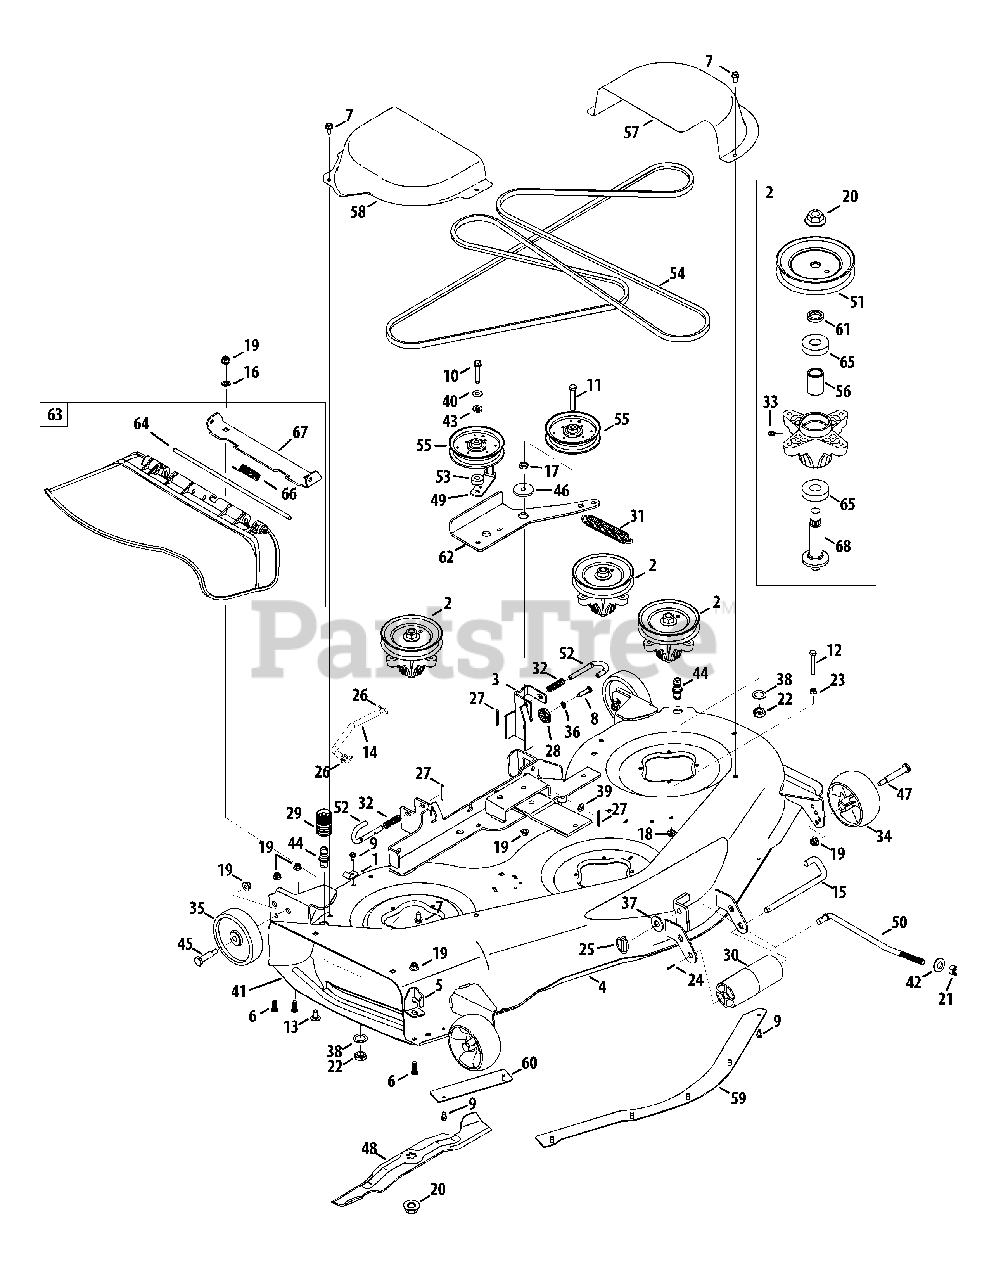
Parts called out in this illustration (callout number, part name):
1	Retainer Hook Brkt.
2	Spindle Assembly
3	Deck Hanger Bracket Ass'y
4	Deck Assembly
5	Chute Deflector Stop
6	Screw, 3/8-16 x 1.0
7	Hex Wash Hd. Tapp Screw. 5/16-18 x .75
8	Hex Bolt 5/16-18 x 1.25
9	Hex Wash S-Tapp Screw 1/4-20 x .50
10	Hex Wash S-Tapp Screw 5/16-16 x 1.875
11	Hex Bolt 3/8-16 x 2.25
12	Hex Hd Cap Screw. 5/16-18 x 2.0 Gr. 5
13	Short Neck Car riage Bolt 3/8-16 x .75
14	Deck Support Rod
15	Roller Pin
16	Push Nut 3/8
17	Jam Nut 7/16 -20, Gr. 2
18	Flange Locknut 5/16-18 Gr. F, Nylon
19	Flange Lock-Nut 3/8-16 Gr. F Nylon
20	Flange Nut 5/8-18
21	Flexlock Nut 1/2-13
22	Hex Nut M16-1.5 DIN 936
23	Hex Nut 5/16-18 hd. (Gr. t5)
24	Cotter Pin 3/32 x 1.0
25	Lynch Pin, .1875
26	Bow Tie Cotter Pin
27	Cotter Pin 1/8" Dia x 1.25
28	Deck adjustment Gear
29	Water Nozzle Adap tor
30	Front Roller
31	Extension Spring 1.0 x 6.10
32	Compression Spring .535 OD x 1.75" Lg.
33	Grease Fitting
34	Deck Wheel 5.0
35	Wheel Ass’y - Deck 5" x 1.38"
36	L-Wash 5/16 ID
37	Flat Washer .531 ID x 1.25 OD x .100
38	L-Washer Internal
39	Flat Washer .344 ID x .688 OD x .065
40	Flat Washer .406 ID x .875 OD x .059
41	Finger Guard
42	Cupped Washer .63 x 1.25 x .18
43	Flat Washer .407 ID x .812 OD x .135
44	Port, Water
45	Shoulder Bolt .498 Dia x 1.53 x 3/8-16
46	Spacer, Shoulder .884 x .190
47	Shoulder Screw
48	Blade 17.90
49	Belt Guard Bracket
50	Front Deck Lift Rod
51	Idler Pulley
52	Deck Release Pin
53	Spacer .406 x 1.0 x .38
54	V-Belt
55	Idler Pulley
56	Spacer .800 x 1.10 x 1.530
57	LH Belt Cover
58	RH Belt Cover
59	Deck Skirt Cen ter
60	Deck Shirt RH
61	Spacer .750 x 1.150 x .230
62	Idler Bracket Arm
63	Chute Ass'y
64	Hinge Pin .3125 x 7.96
65	Ball Bearing 20 x 47 x 14:6204:DS
66	Torsion Spring
67	Chute Bracket
68	Spindle Shaft 4.1250
